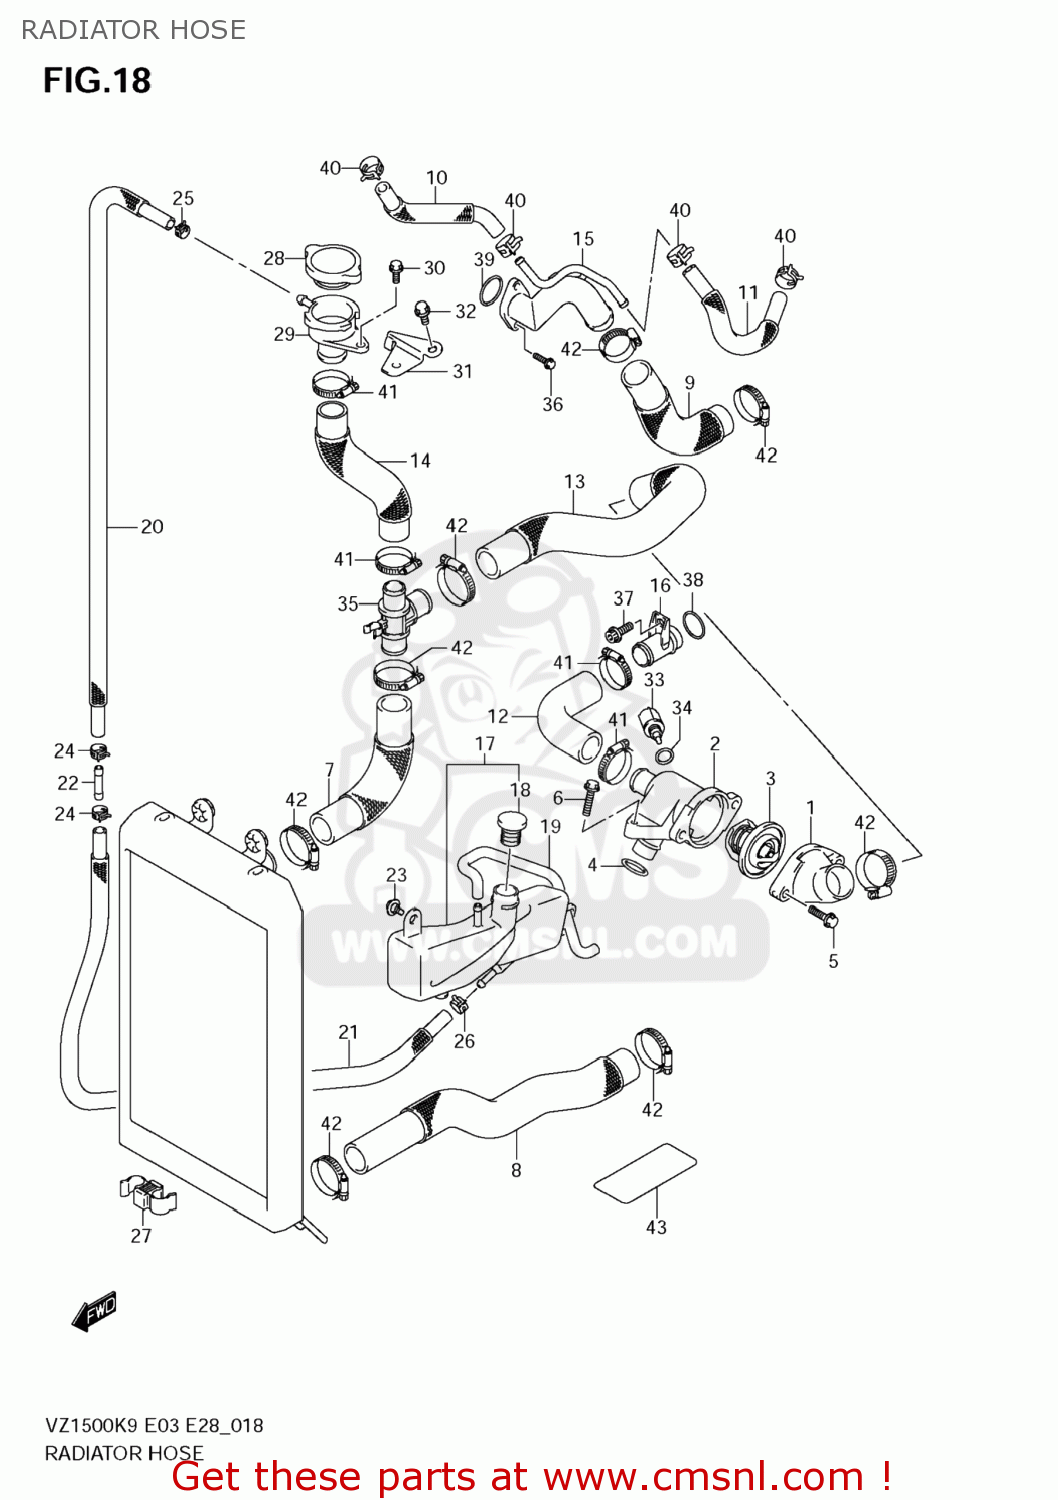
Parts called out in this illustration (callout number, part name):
1	COVER,THERMOSTAT
2	CONNECTOR,THERMOSTAT INLET
3	THERMOSTAT,WATER
4	O RING(D:3.2,ID:17.8)
5	BOLT
6	BOLT
7	HOSE,RADIATOR INLET
8	HOSE,RADIATOR OUTLET
9	HOSE,CYLINDER INLET
10	HOSE,WATER BYPASS UPR
11	HOSE,WATER BYPASS LWR
12	HOSE,RR CYLINDER HEAD OUTLET
13	HOSE,THERMOSTAT OUTLET
14	HOSE,CONDUCTION
15	PIPE,CYLINDER WATER INLET
16	UNION,CONNECTOR HOSE
17	TANK ASSY,RESERVOIR
18	CAP,RESERVOIR TANK
19	HOSE,RESERVOIR TANK OVFL
20	HOSE,RESERVOIR TANK INLET
21	HOSE(5X9X600)
22	UNION
23	BOLT(6X12)
24	CLIP
25	CLIP
26	CLAMP(L:125)
27	CLAMP(L:190)
28	CAP,RADIATOR(1.1)
29	CONDUCTION,RADIATOR
30	BOLT
31	BRACKET,CONDUCTION
32	BOLT
33	SENSOR,TEMP
34	GASKET(12X17X1) (NAS)
35	JOINT,3 WAY
36	BOLT(6X16)
37	BOLT
38	O RING(D:3.2,ID:17.8)
39	O RING(D:2.4,ID:26.2)
40	CLAMP
41	CLAMP
42	CLAMP
43	TAPE,RR FENDER
